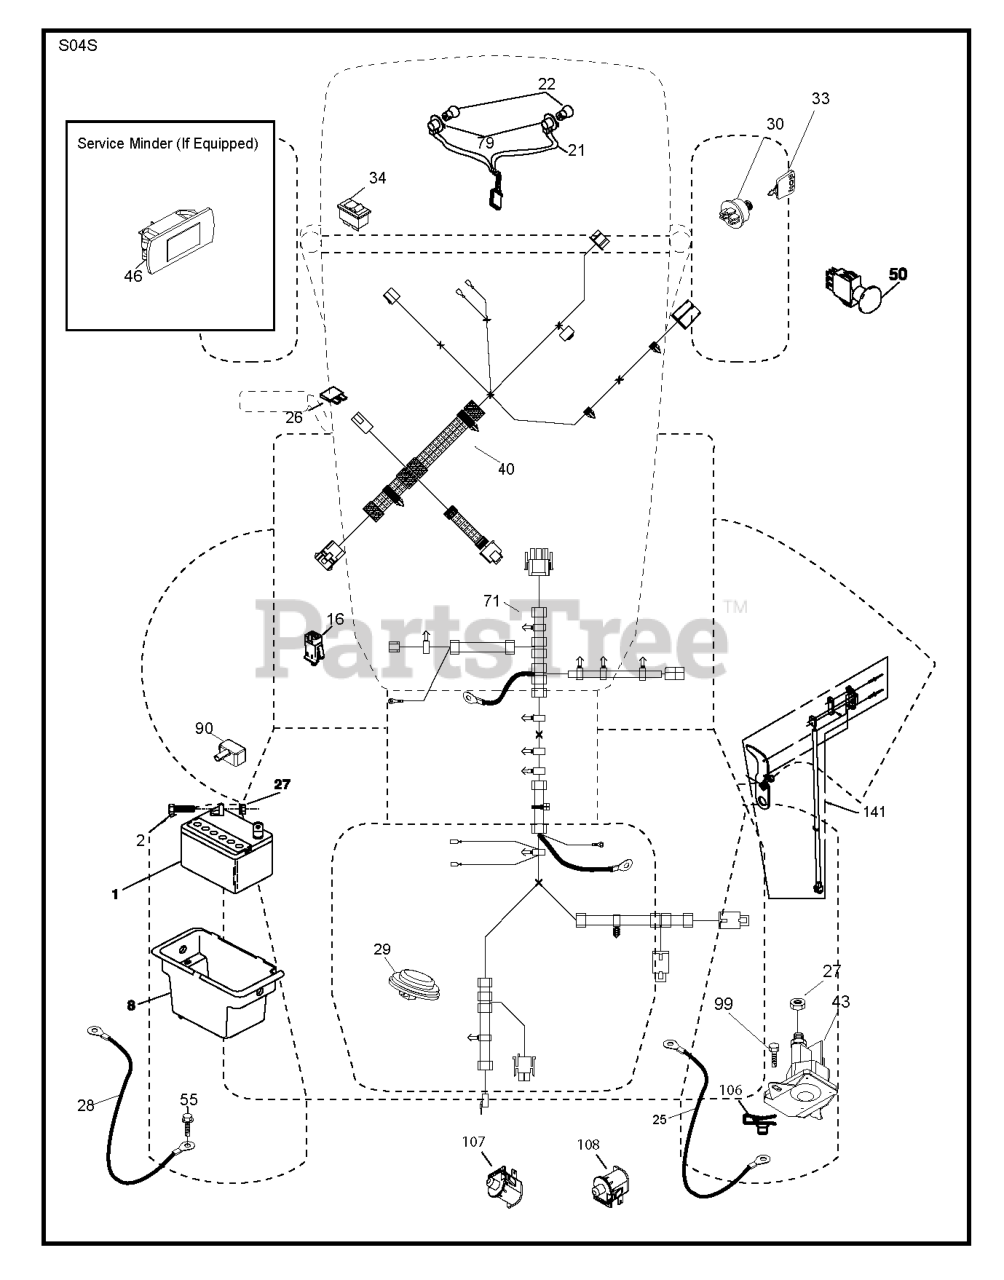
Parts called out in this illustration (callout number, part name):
1	Battery, Dry 30 Amp
2	BOLT.HEX.1/4.X.3/4.DICHROMATE
8	BOX.BATTERY.LT/SRD
16	SWITCH INTERLOOK PUSH-IN
21	HARNESS.LIGHT W/4152J BULBS
25	CABLE.BATTERY.20.RED.8 AWG
26	FUSE 20AMP
27	NUT
28	CABLE.GROUND.REAR.BATTERY.8G
29	SWITCH.SEAT.DELTA.OPC.
30	SWITCH.IGN.DELTA.W.LGH.ROS
33	KEY.CHAIN.BLISTER.PACK.GEN.USA
40	WIRING HARNESS
43	SOLENOID.W/BRASS.PLUNGER
46	GUAGE.SRVCMNDR.HRMTR.
50	RP.PTO.SWITCH.8 TERMINAL.BLACK
55	SCREW 5/16"
71	RP.HARNESS.ELEC.CHASSIS.SRD
79	BULB HOLDER ASM.
90	COVER.TERMINAL.BATTERY
99	SCREW HEXWSHR 1/4-20X3/4
106	1/4-20 U NUT
107	SWITCH.SNAPMOUNT.NO.#2
108	SWITCH.SNAPMOUNT.NC
141	KIT T2.ROS 71677
